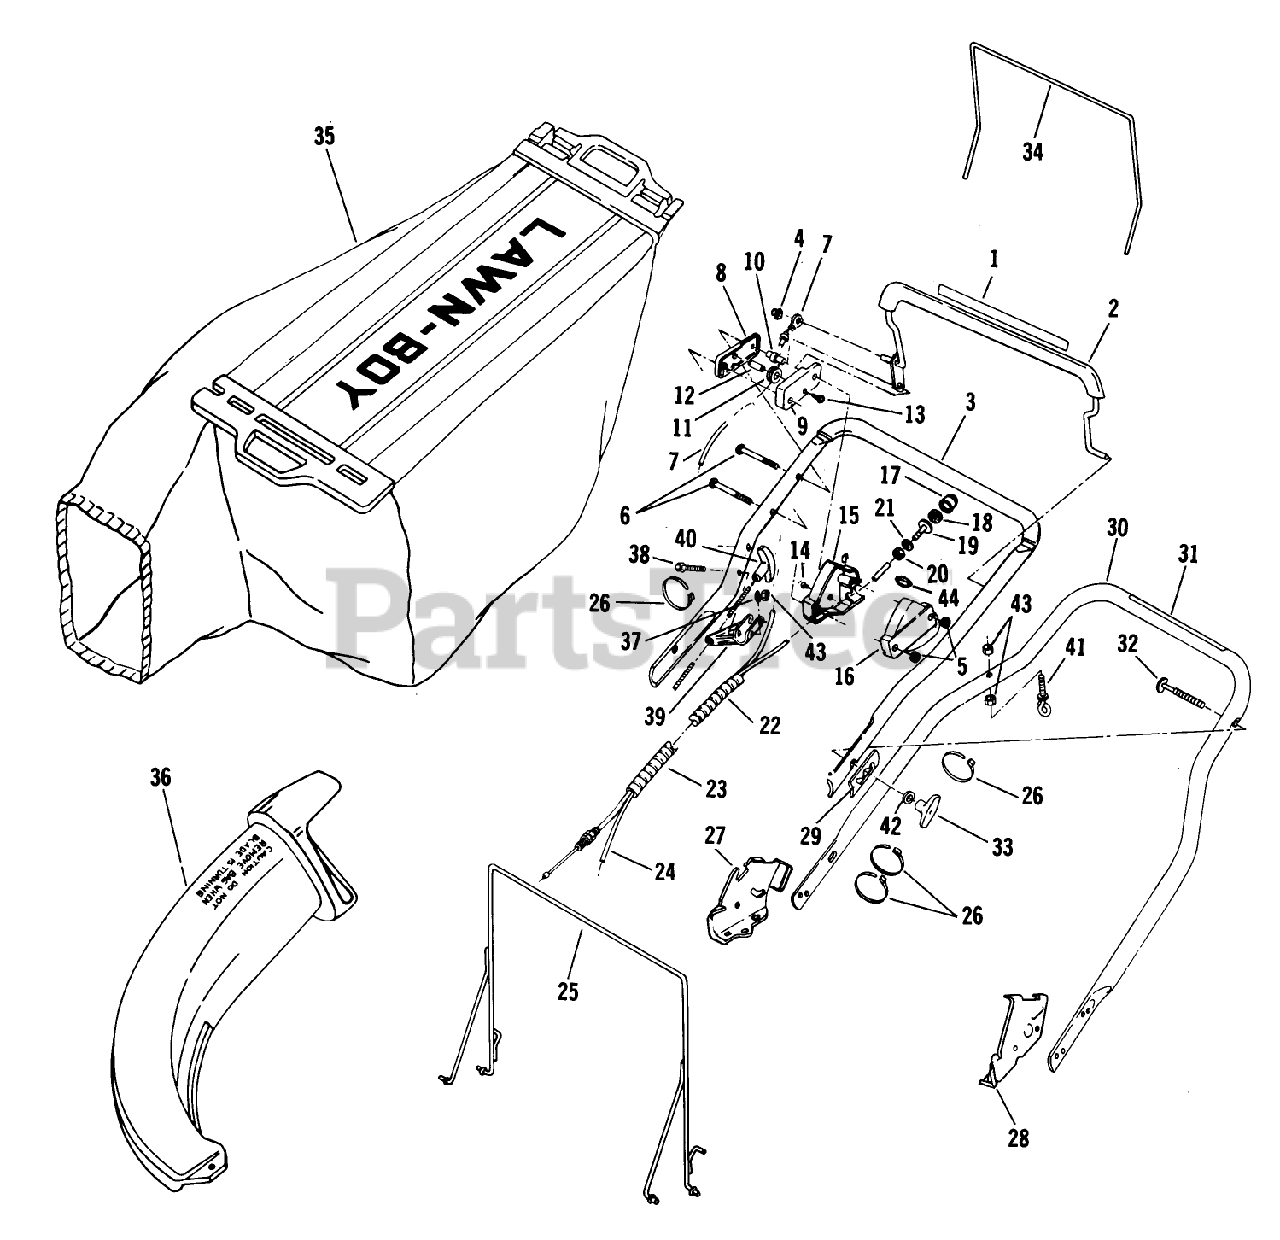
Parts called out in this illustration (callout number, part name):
2	Control Lever Assembly
5	NUT C/LOCK E
10	COLUMN
12	PIN SKF
13	SCREW
18	FILTER S
21	LOCKNUT S
25	HANGER AY
29	BRACKET R/B 613462
32	BOLT QUALITY
33	NUT-WING
34	HANGER
37	WASHER
40	HANDLE,STARTER
41	EYE BOLT WAS MFG
42	WASHER-CURVED
43	LOCKNUT E
